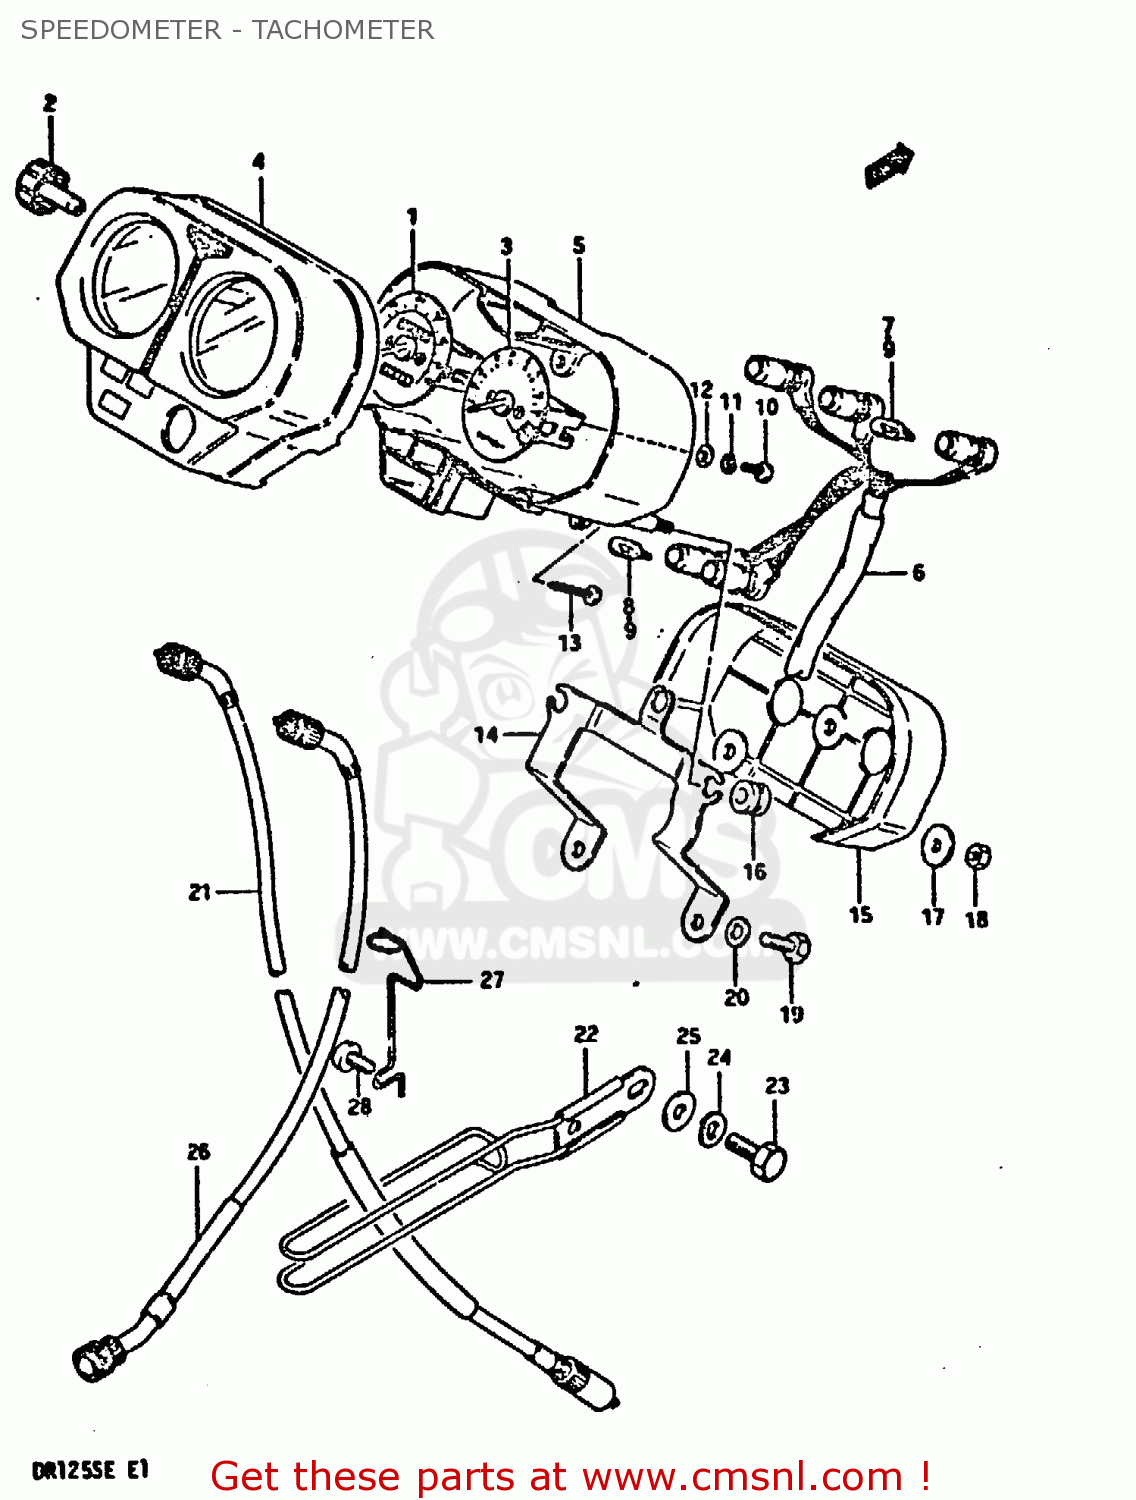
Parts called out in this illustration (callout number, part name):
1	SPEEDOMETER
2	KNOB,TRIP
3	TACHOMETER
4	HOOD, METER
5	CASE,INNER
6	SOCKET
7	BULB(6V1.7W,STANLEY,A61A)
8	BULB(6V,3W)
9	BULB(12V3.4W,T10)
10	SCREW 4X10
11	LOCK WASHER
12	WASHER
13	SCREW
14	BRACKET,METER
15	COVER
16	CUSHION
17	WASHER (5.5X16X1.2)
18	NUT
19	BOLT
20	WASHER
21	CABLE ASSY,SPE
22	GUIDE,CABLE
23	BOLT 8X12
24	LOCK WASHER
25	WASHER
26	CABLE,TACHOMETER
27	GUIDE,TACHOMETER CABLE
28	SCREW, FRONT
